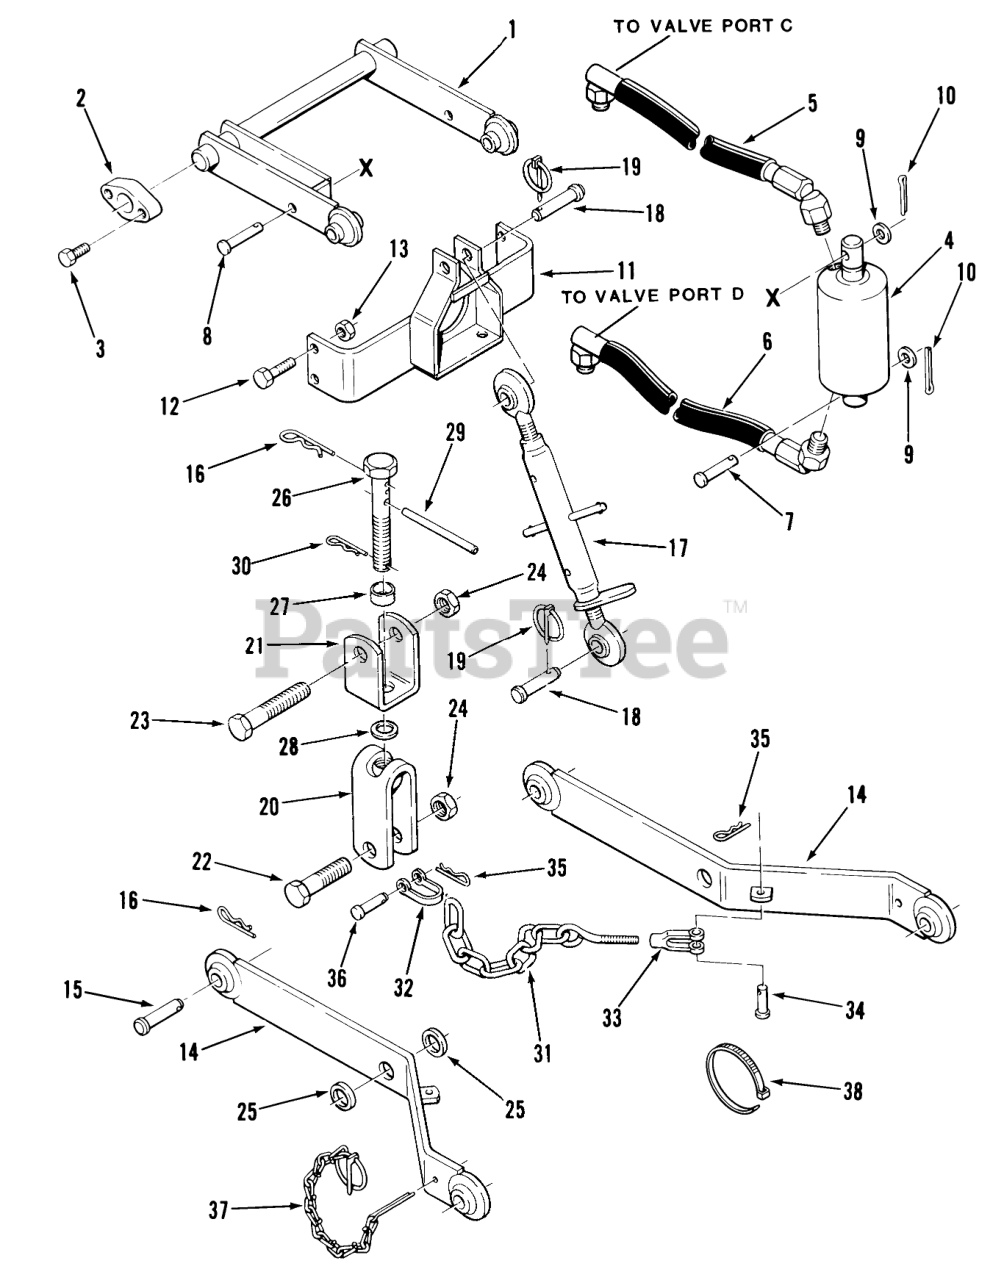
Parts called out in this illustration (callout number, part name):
1	LIFT BAR ASSEMBLY R
2	BLOCK
3	BOLT
4	Cylinder
5	Hydraulic Hose 26.5 in. Long ( 59.7 cm)-w/973310 O-rings-Top of Cylinder Port C
6	Hydraulic Hose 28.75 in. Long (73 cm)-w/973310 O-rings-Bottom of Cylinder Port D
8	Clevis Pin 1/2 x 2 3/4
9	Washer
11	ASSY UPPER LINK PIVO
12	Bolt
13	NUT
14	ASSY LOWER HITCH LNK B
15	PIN 5/8 DIA LINK ATT
16	Hairpin
17	Link-Upper
18	PIN HITCH UPPER LINK
19	HITCH PIN ASSY
20	Adjuster
21	LIFT BAR
22	Bolt 3/-10 x 3
23	Bolt 3/-10 X 3 1/2
24	E.S. Nut 3/4-10
25	SPACER
26	Adjusting Bolt
27	Spacer
28	WASHER
30	Hairpin Cotter
31	Sway Chain
32	Clevis
33	CLEVIS
36	Clevis Pin
37	Klik Pin
38	PLASTIC TIE
